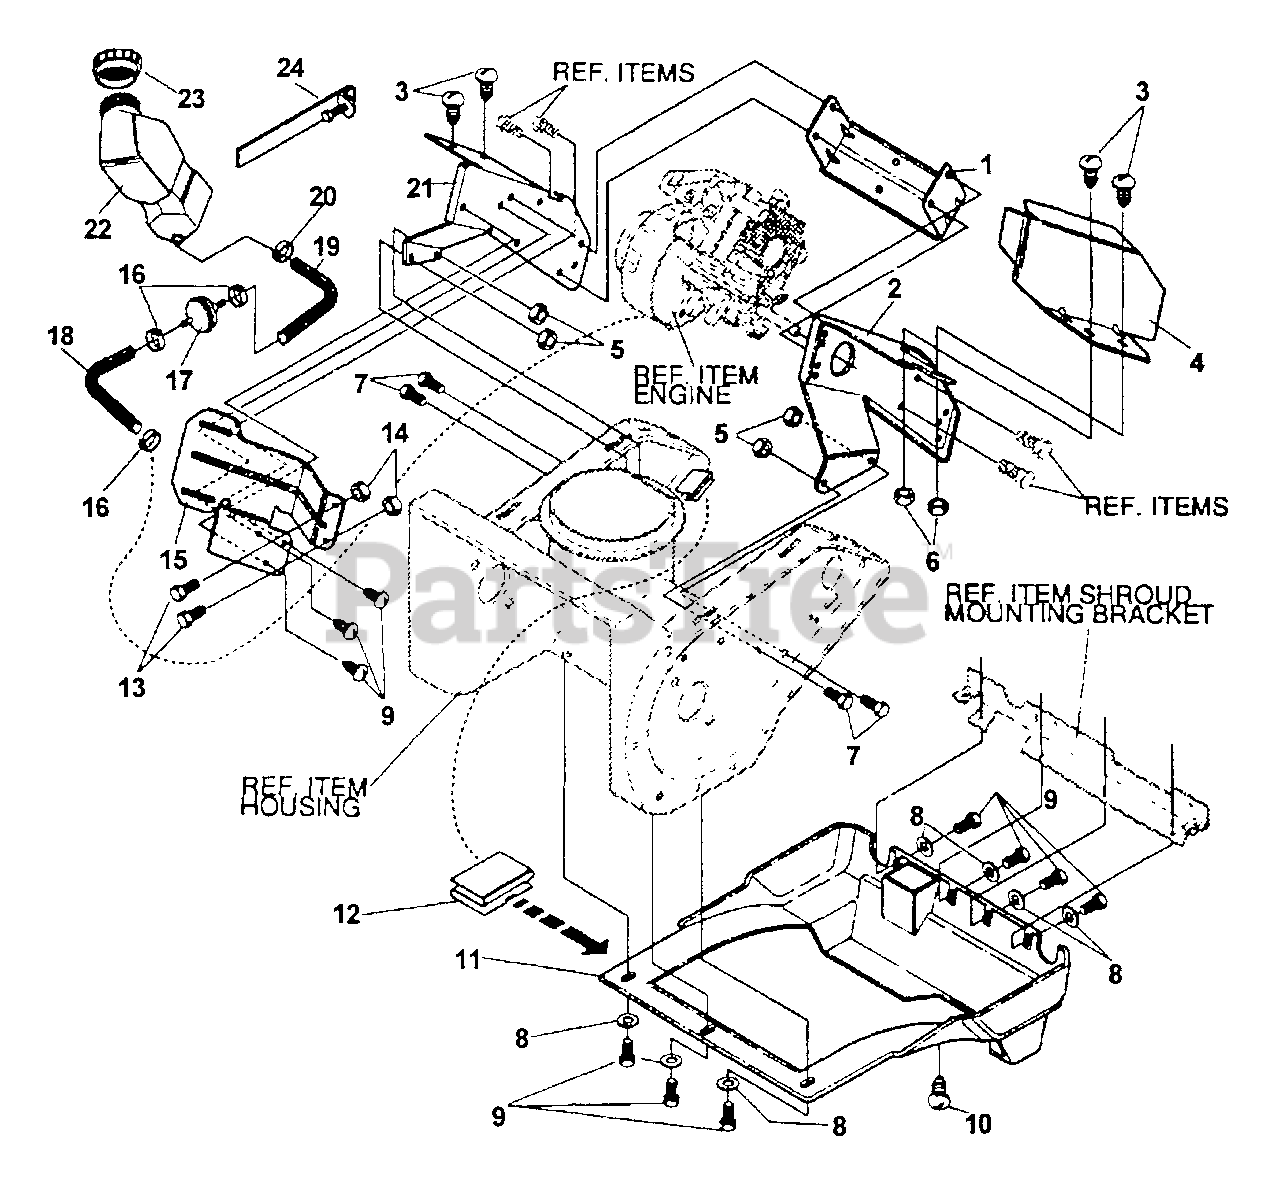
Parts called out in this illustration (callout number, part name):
1	SUPPORT, FRAME
2	PLATE, REAR MOUNT -- LEFT
3	SCREW - 1/4-20 X 5/8"
4	SHIELD, HEAT
5	NUT - 5/16-18
6	LOCKNUT - 1/4-20
7	SCREW - 5/16-18 X 1/2"
8	WASHER
9	SCREW - 10-24 X .63"
10	SCREW - 10-16 X .50"
11	SHROUD, BOTTOM
12	CLIP
13	SCREW - 10 X 24 X .50"
14	LOCKNUT - 10-24
15	BRACKET, FUEL TANK
16	CLAMP, HOSE
17	FILTER, FUEL
18	TUBING, GAS LINE 30"
19	TUBING, GAS LINE 8"
20	CLAMP, HOSE
21	PLATE, REAR MOUNT -- RIGHT
22	TANK, FUEL - 6.2 QUART
23	CAP, FUEL
24	CLAMP, WORM DRIVE
